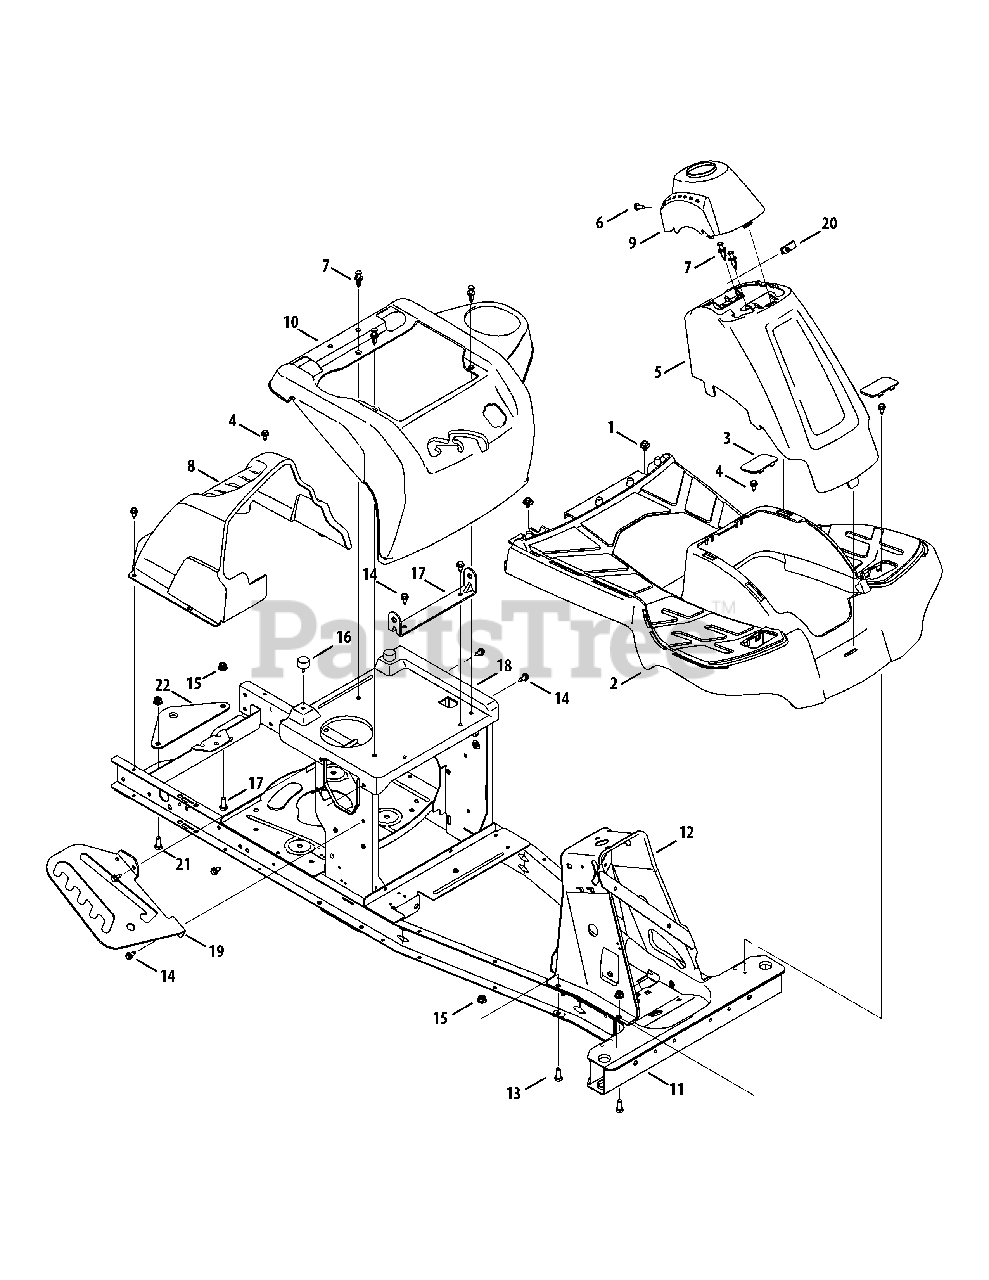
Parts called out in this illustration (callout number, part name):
1	Screw, 1/4-20 x .500
2	Running Board
3	Running Board Plug
4	Shoulder Screw, .368 X.113: 1/4-20
5	Column Cover (MTD Red)
6	Machine Screw, 1/4-20, 0.750
7	Rivet, .3125
8	Drive Cover
9	Steering Column Cap (MTD Red)
10	Fender (MTD Red)
11	Frame Assembly
12	Column Assembly
13	Hex Washer Screw, 5/16-18 x .75
14	Tap Screw, 1/4-20, .625
15	Hex Locknut, 5/16-18
16	Bumper, .62 Dia. x .50
17	Seat Pivot Bracket
18	Seat Plate
19	De ck Lift Index Bracket
20	U-type Speed Nut, 1/4-20
21	Hex Head Screw, 5/16-18, .75
22	Hitch Plate
